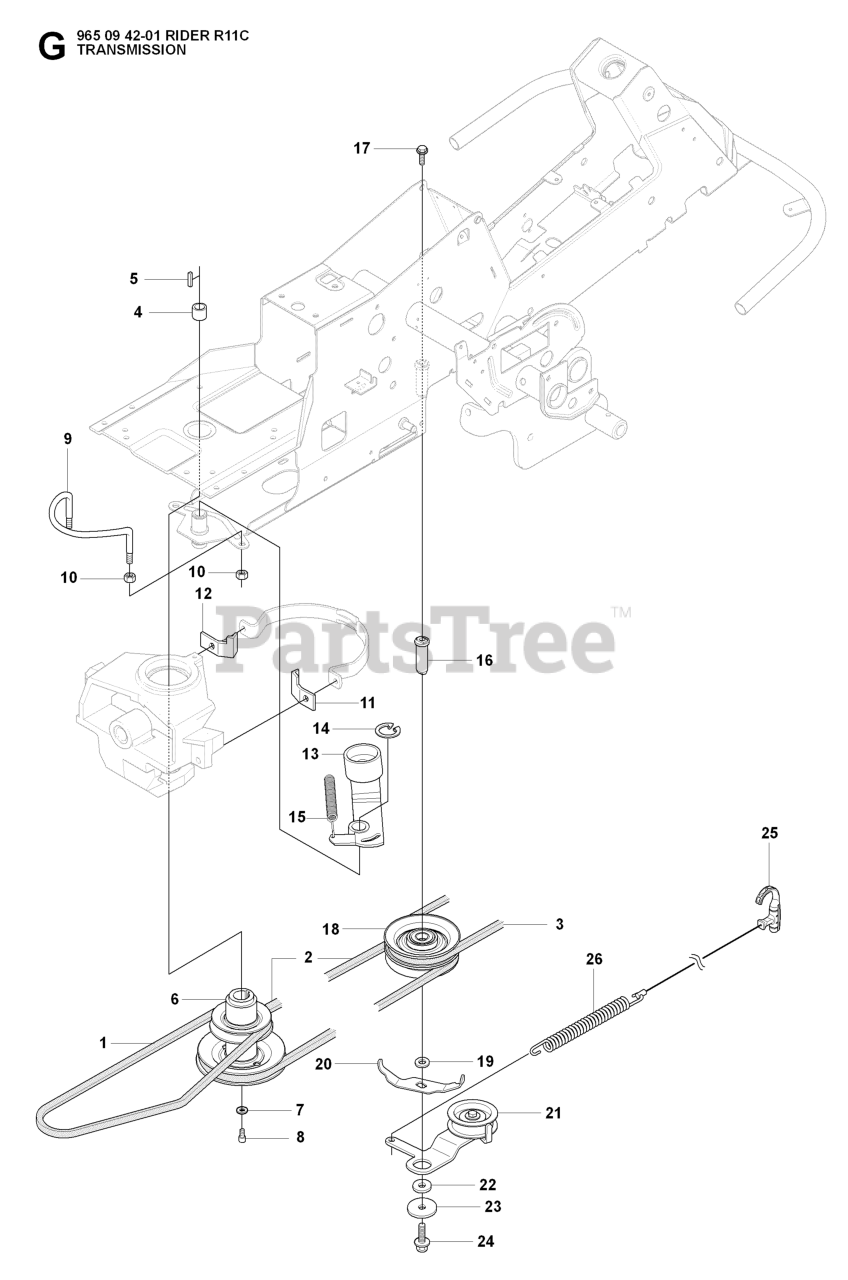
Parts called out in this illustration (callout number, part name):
1	TRANSMISSION BELT
2	BELT
3	BELT
6	Pulley Cpl
9	BELT GUIDE
10	NUT
11	Belt Guide Cpl., Right
12	Belt Guide Cpl.,Left
14	RETAINING RING SGA 25
16	SHAFT
20	BELT GUIDE
21	BELT TENSIONER ASSY
24	BOLT
